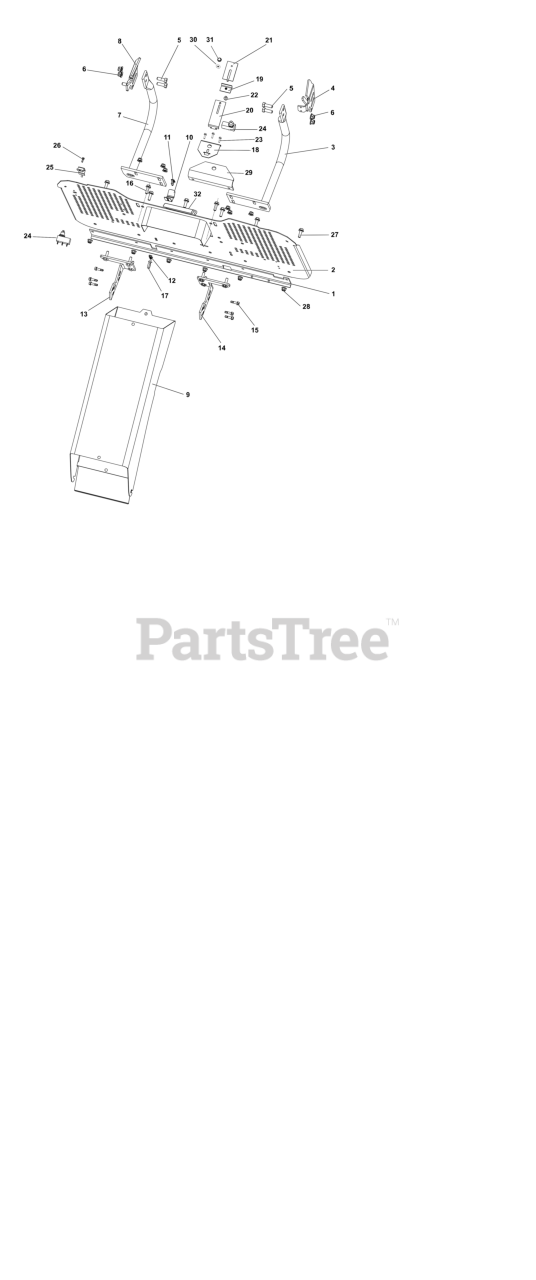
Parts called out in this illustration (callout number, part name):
1	PLATE, Reinforcement
9	CHUTE, Discharge
24	MICROSWITCH
25	SWITCH, Cover
